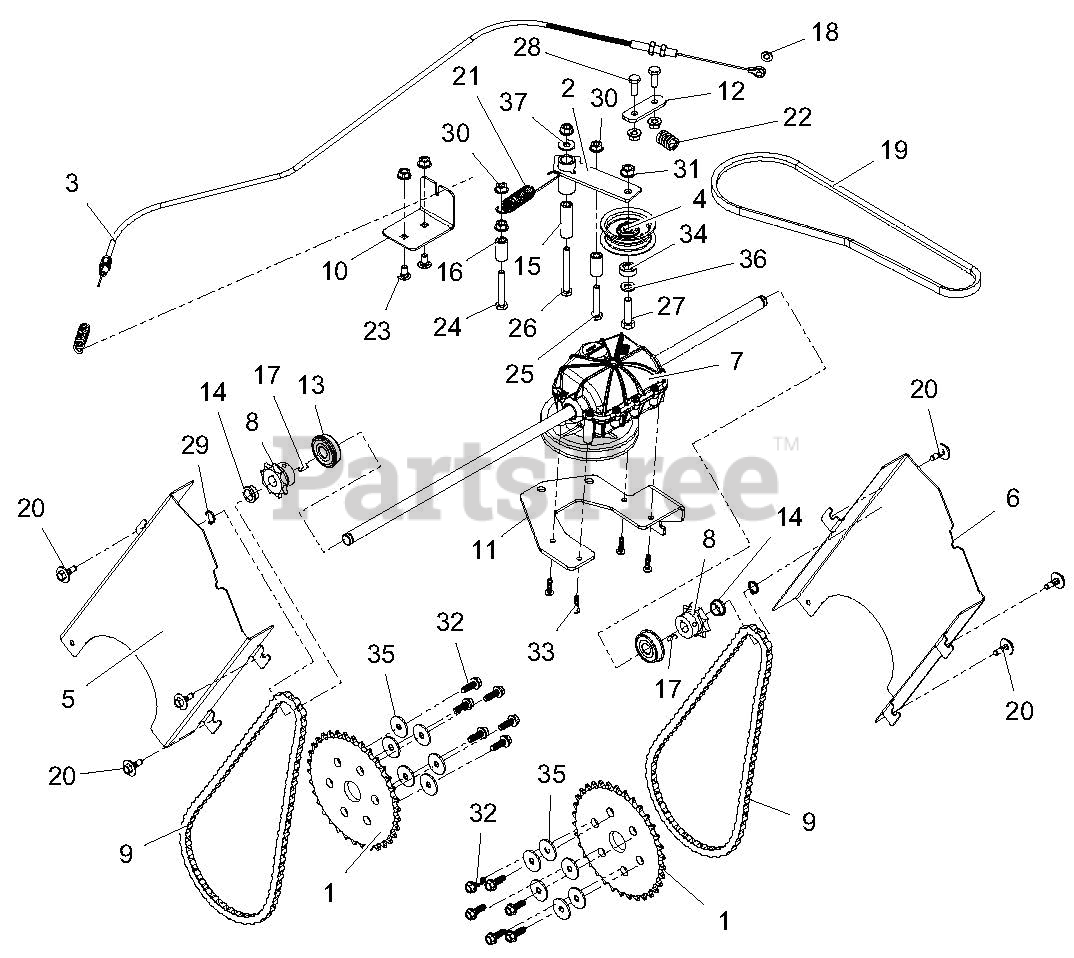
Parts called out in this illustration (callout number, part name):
1	SPROCKET, DRIVE - 41 34T FLAT
2	WLDMT, IDLER ARM
3	CABLE, TRACTION - APV DRIVE
4	IDLER, FLAT - 2.00"
5	GUARD, BELT - RIGHT APV
6	GUARD, CHAIN - LEFT APV
7	TRANS, DRIVE - GT MA502
8	SPROCKET,DRIVE - 41 9T #404KW
9	CHAIN, ROLLER - #41 64 PITCHES
10	MOUNT, CABLE - APV TRACTION
11	MOUNT, TRANSMISSION - APV
12	PLATE, RETAINER - APV TRANS
13	BRG-BALL .50X1.38X.438 SEALED
14	BSHG,FLANGE .500X.625X.270X.75
15	BSHG, SLV .265X.505X1.665
16	BSHG, SLV .265X.505X.995
17	KEY-WDRF .125X.50X.20 (HRDEND)
18	NUT-PUSH .25X.50 O.D.
19	V-BELT, 3L-WRAPPED
20	SCR-TAP .25-20X.5 CAPTIVE
21	SPRG, EXTENSION
22	SPRG, COMPRESSION
23	@BLT-RDHDSQNK .25-20X.50 G5YZ
24	@BLT-HEX .25-20X1.75 GR5 YWZC
25	@BLT-HEX .25-20X1.50 GR5 YWZC
26	@BLT-HEX .25-20X2.25 GR5 YWZC
27	@BLT-HEX .31-18X1.25 GR5 YWZC
28	@BLT-HEX .25-20X.75 GR5 YWZC
29	RG-RTNG-EXT .500X.050 (SNAP)
30	@NUT-LK-TOP-FLG .25-20 YWZC
31	@NUT-LK-TOP-FLG .31-18 YWZC
32	SCR-HEX .25X14-.75
33	SCR-TAP 10-14X.75PLSTITE BLKOX
34	SPCR, BRG .315X.500X.358X.281
35	WSHR-FL-STL .281X1.000X.063
36	WSHR-FL-STL .323X.625X.062 YWZ
37	@WSHR-FL-STL.312X.734X.065 YWZ
